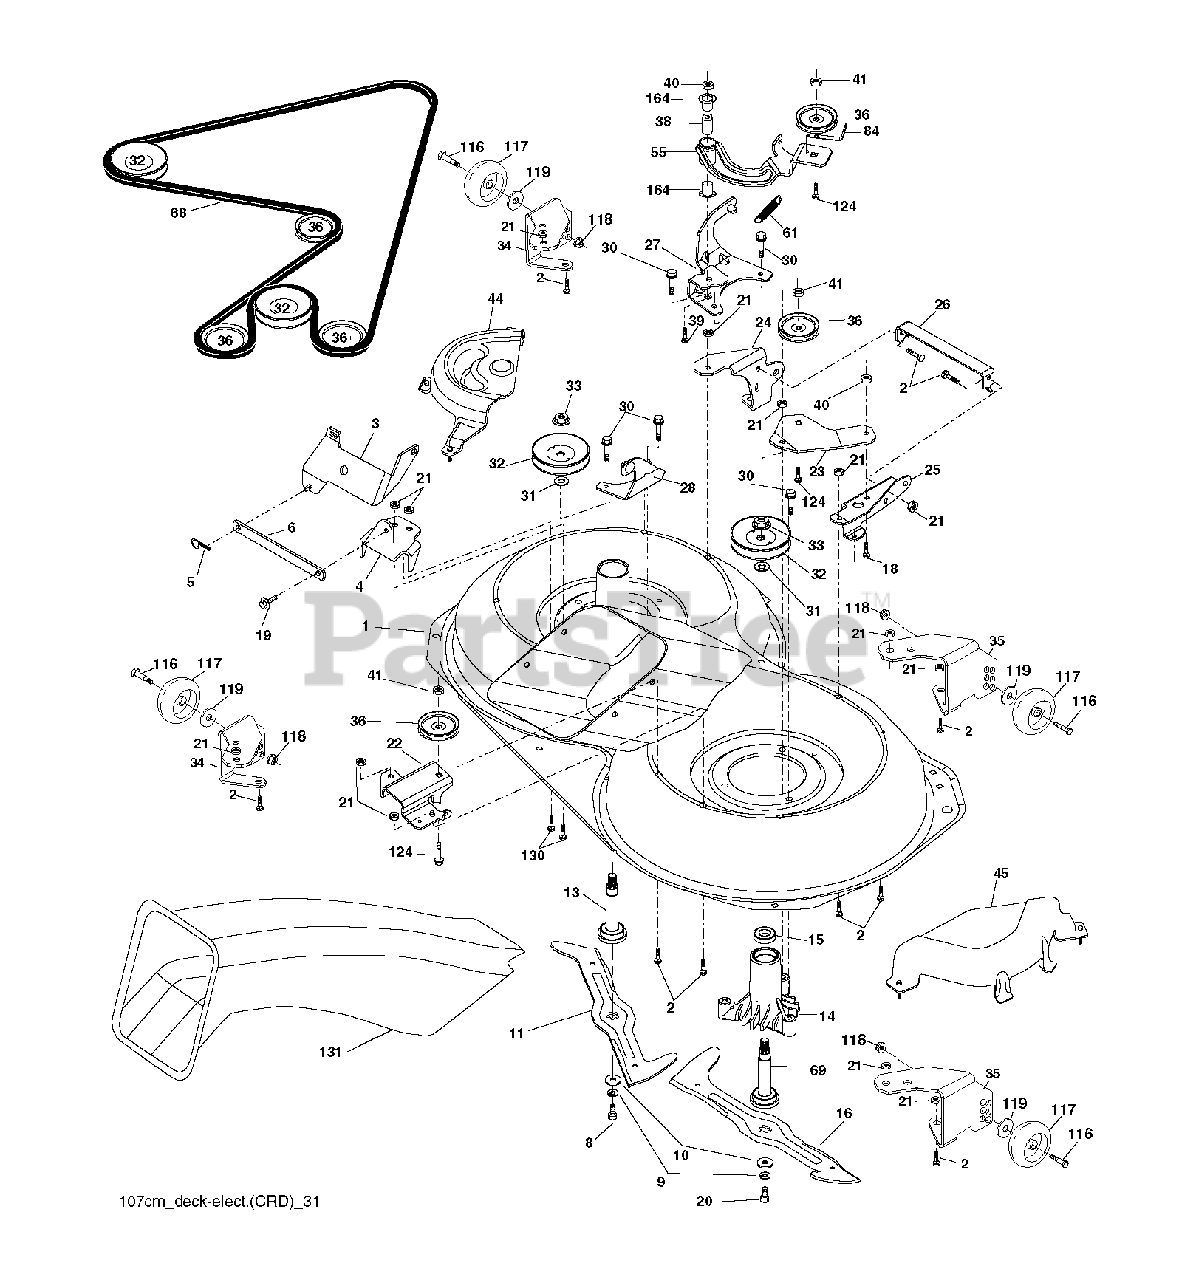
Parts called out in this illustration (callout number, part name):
2	BOLT
3	BRACKET.ASM.BAR.SWAY.CHASS
5	RETAINER-SPRNG RB
6	BAR SWAY
9	LOCKWASHER
10	WASHER.BLADE
11	BLADE.3N1.LH.CRD
13	SHAFT ASM VENT
14	HSG MANDREL
16	BLADE.3N1.RH.CRD
19	BOLT SHD 5/16-18
21	LOCKNUT
22	BRACKET
23	BRACKET
27	BRACKET
30	SCREW, WASHER HEAD
31	WASHER.SPACER.MANDREL
33	NUT.FLANGE.LOCK.TOP
36	PULLEY.IDLER.4.25
40	LOCKNUT
41	NUT LOCK FLG 3/8-16 UNC
68	HEX-BELT 107 MOWER
69	SHAFT.ASM.W/LWR.BRG.RH.THREAD
84	KEEPER, BELT IDLER
116	BOLT.SHOULDER.3/8-16X3-5/8
117	WHEEL. GUAGE RALLY
118	NUT LOCK FLG 3/8-16 UNC
124	BOLT.3/8-16X1.50
131	CHUTE BAGGER
164	BRNG T
